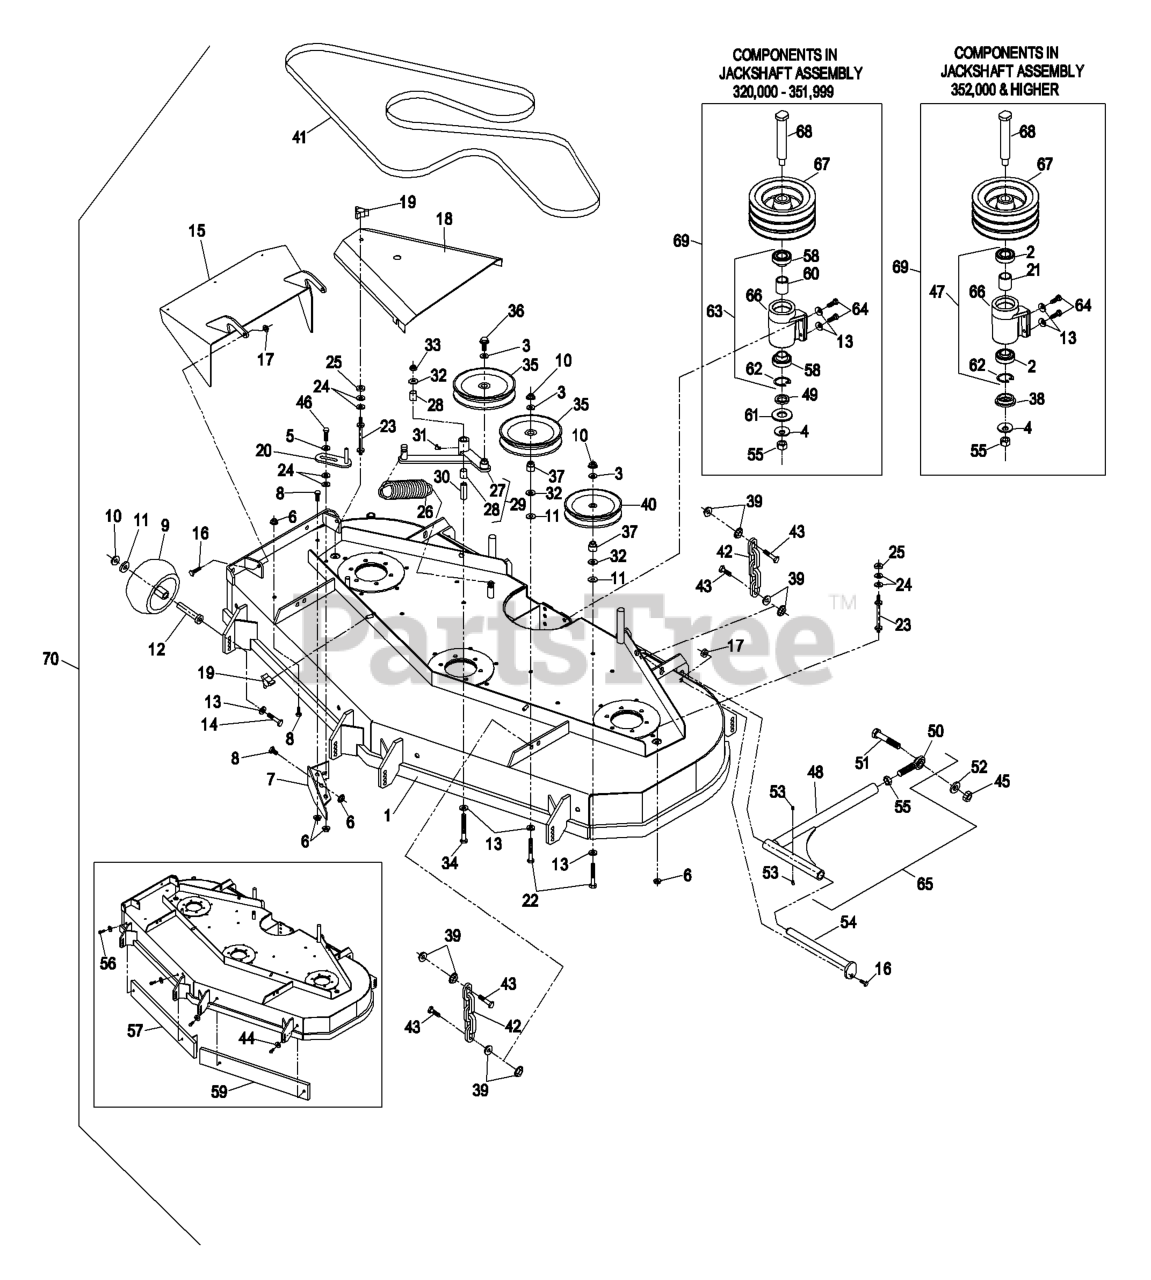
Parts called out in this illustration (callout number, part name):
2	BEARING-JACKSHAFT
3	WASHER-FLAT
4	WASHER-SPRING
5	WASHER-SPRING
7	WLD,BAFFLE DISCHARGE
8	SCREW-HH
9	ROLLER-SCALP, ANTI
10	NUT-HHF, WHIZ
12	BUSHING-ROLLER
13	WASHER-BELLEVILLE
14	SCREW-HH
16	SCREW-HH
17	NUT-LOCK, NI
18	SHIELD,BELT
19	KNOB-3 PRONG
20	GUIDE-BELT
21	SPACER-BEARING
22	SCREW-HH
23	STUD-SHIELD, BELT (SHORT)
24	WASHER-FLAT
28	SLEEVE-BEARING
30	BUSHING
31	FITTING-GREASE, 90 DEG
32	WASHER-FLAT
33	NUT-LOCK, NI
36	SCREW-HHF
37	BUSHING-IDLER
38	SPACER-GUARD, BOTTOM
40	PULLEY-IDLER
41	BELT,BLADE DRIVE
42	CHAIN-LIFT, DECK
43	SCREW-HH
44	WASHER-SPRING
45	NUT-HEX
46	SCREW-HH
49	SPACER-PULLEY/BEARING
50	BALLJOINT-SPHERICAL
51	SCREW-HH
52	WASHER-LOCK
53	FITTING-GREASE
54	PIN-STRUT
55	NUT-HEX
56	SCREW-HH
57	WEIGHT BAR ASM
58	BEARING
60	SPACER-BEARING
61	GUARD-BEARING, BOTTOM
62	RING-SNAP
63	Asm,Jackshaft Housing W/Brgs
64	SCREW-HH
65	STRUT ASM
68	JACKSHAFT,LAZER XP
69	ASM,JACKSHAFT
70	Complete Deck Assy
